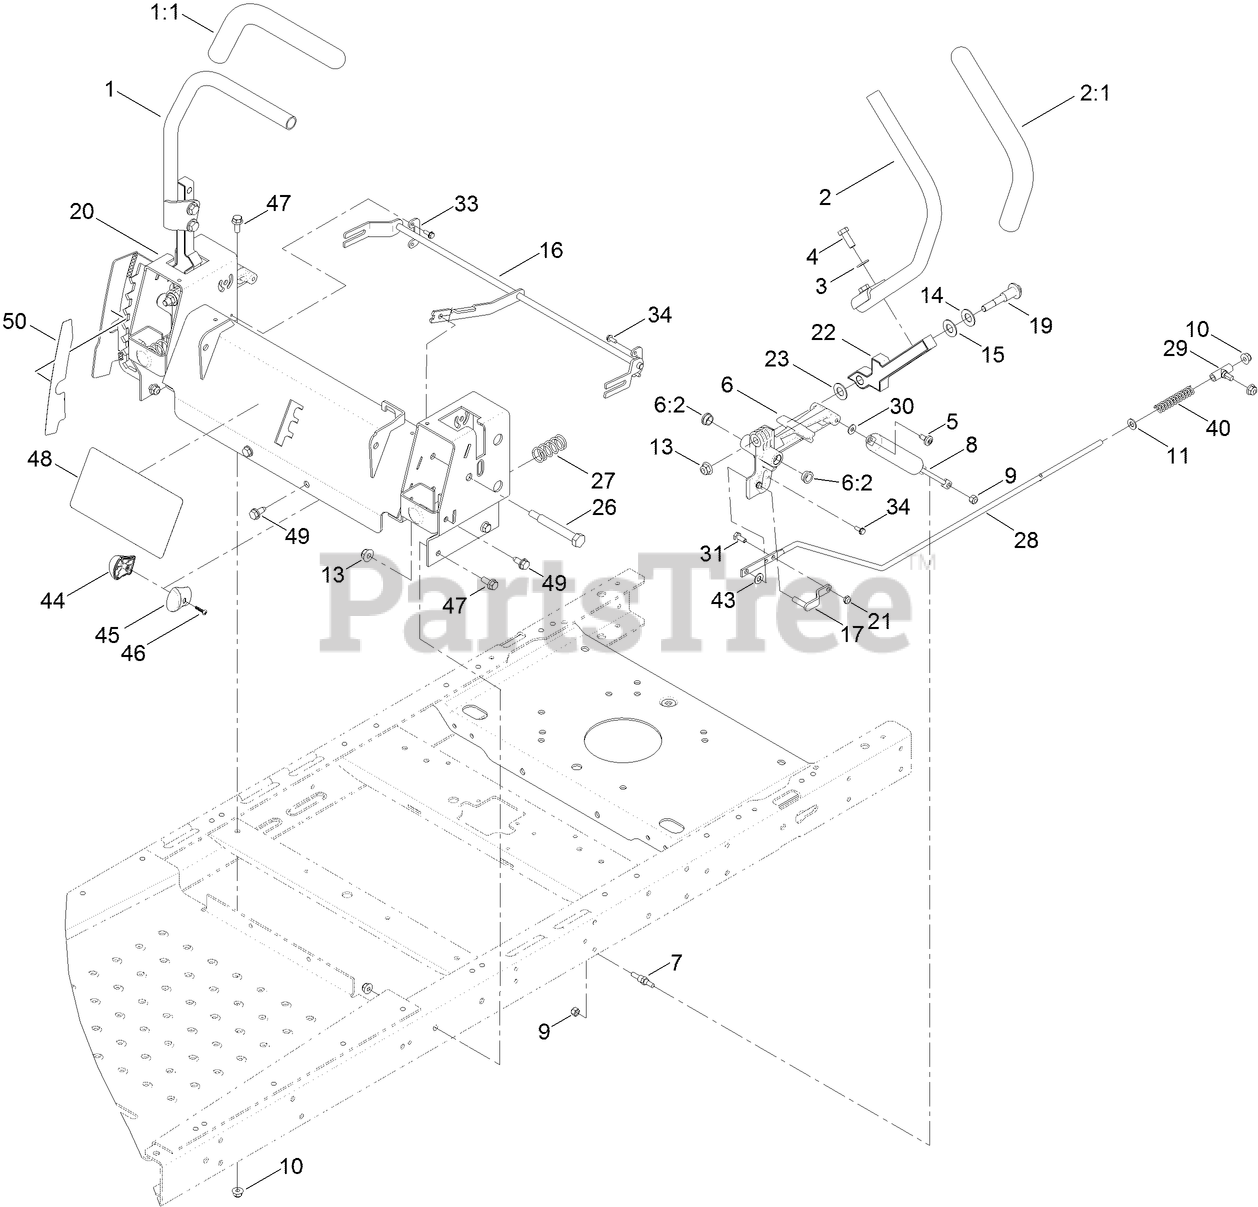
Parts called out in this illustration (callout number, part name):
1	HANDLE-CONTROL, RH
2	HANDLE-CONTROL, LH
3	WASHER-FLAT
4	SCREW-HH
5	SCREW-SHOULDER
6	ACTUATOR ARM ASM
6:2	BUSHING-FLANGE
7	STUD-DAMPER
8	DAMPER
9	NUT-LOCK, NI
10	NUT-HF, NI
11	WASHER-PLAIN
13	NUT-HF, NI
14	WASHER-BELLEVILLE
15	WASHER
19	BOLT-PIVOT
21	NUT-LOCK, NI
23	WASHER-NYLON
26	BOLT-PIVOT
27	SPRING-RETURN
28	ROD-HYDRO
29	MOUNT-ROD, HYDRO
30	WASHER
31	SCREW-HH
33	RETAINER
34	SCREW-TAPTITE
40	SPRING-RETURN, NEUTRAL
43	SPACER-NYLON
46	SCREW-PPH
47	SCREW-HHF
48	DECAL-CONTROL, SPEED
49	SCREW-HWHTF
50	DECAL-HOC
